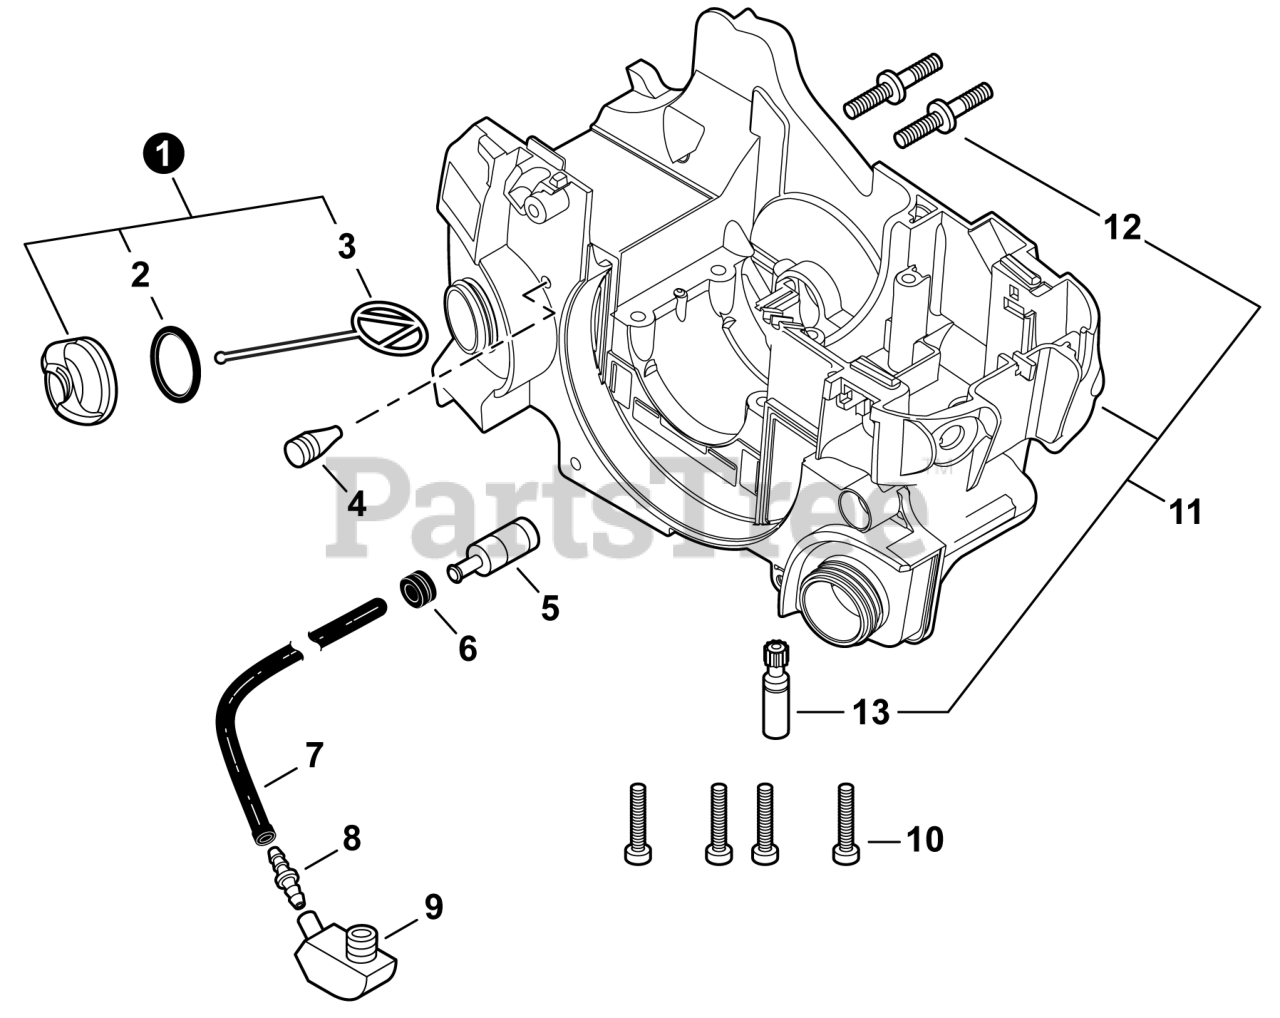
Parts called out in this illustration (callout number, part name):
1	CAP ASSY - BLACK
2	O-RING 18
3	FUEL CAP CONNECTOR (L=60MM)
4	CHECK VALVE
5	FILTER, OIL
7	PIPE 3×6×185 MM BLACK
8	CONNECTOR, PIPE
9	GROMMET, OIL
10	BOLT, TORX 5×30
11	ENGINE CVR ASY CS-310/352 '20
12	BOLT, STUD 8
13	AUTO-OILER ASSY
